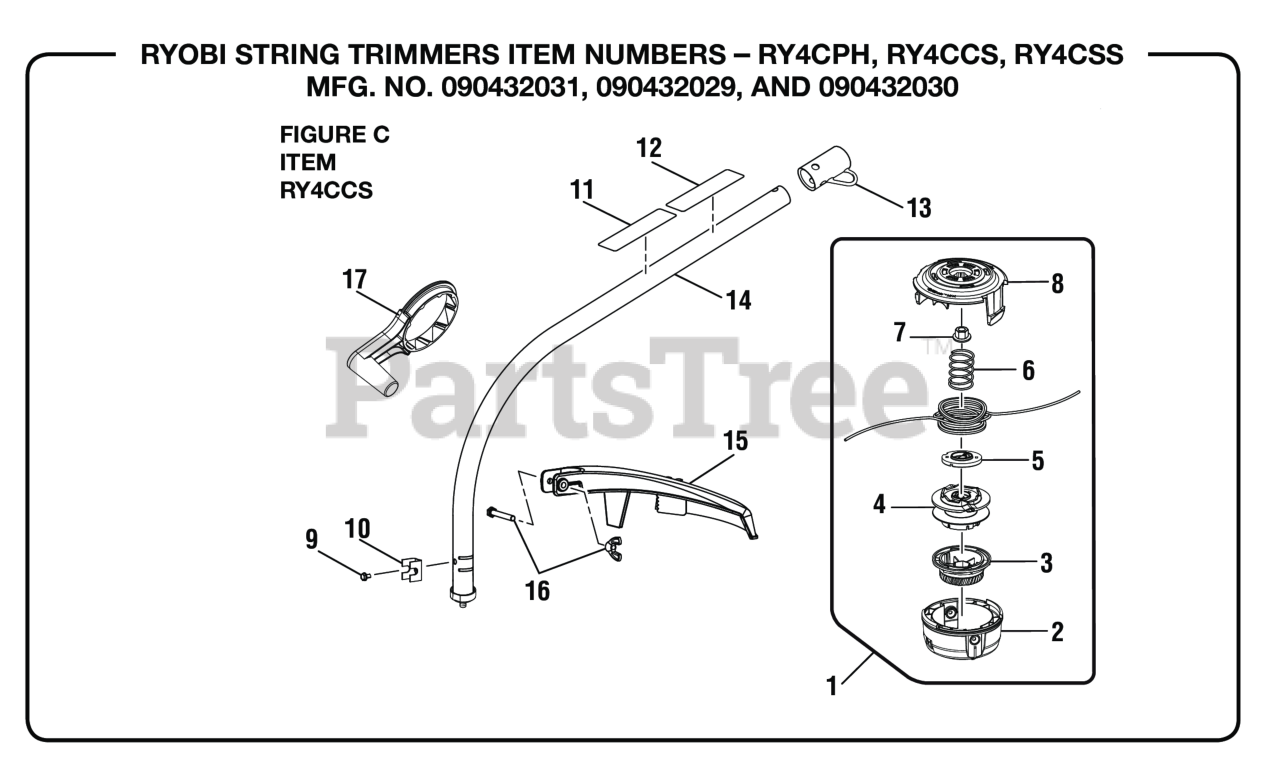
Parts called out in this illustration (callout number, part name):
1	Trimmer Head Assembly (.095)
2	Lower Housing
3	Bump Knob (Green)
4	Spool Assembly
5	String Guide
6	Compression Spring
7	Flange Nut (M8)
8	Upper Housing
9	Screw (#10-32 x 3/8 in., Hex Washer Hd. S.T.)
11	Ryobi EXPAND-IT Label
12	Warning Icon Label
13	Storage Hanger Cap
14	Curved Shaft Assembly
15	Grass Deflector Assembly
16	Fastener Parts Kit
17	Crank Handle Assembly
